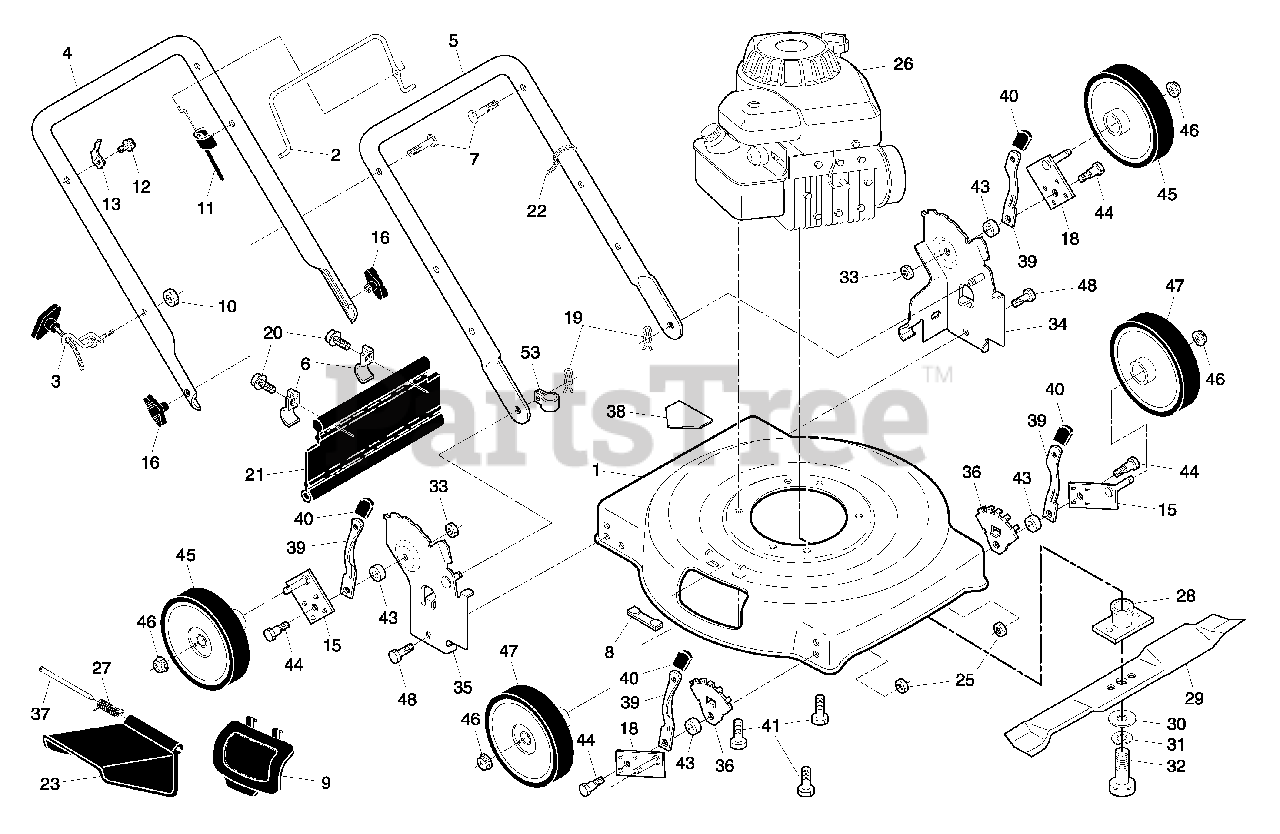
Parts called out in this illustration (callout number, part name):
1	Kit, Housing
2	Control Bar
3	Rope Guide
4	Upper Handle
5	Lower Handle
6	Shoulder Bolt 5/16-18 x 1/2
7	Handle Bolt 5/16-18
8	Clip, Closeout
9	Mulcher Plate
10	Locknut, Hex 1/4-20
11	Engine Zone Control Cable
12	Screw, Hex Head, Threaded, Rolled #10-24 x 1/2
13	Up-Stop Bracket
15	Axle Arm Assembly, Left Front & Right Rear
16	Handle Knob
18	Axle Arm Assembly, Right Front & Left Rear
19	Hairpin Cotter
20	Screw, Tapping, Hex Washer Head #10-24
21	Rear Deflector
22	Wire Tie
23	Discharge Guard
25	Nut, Hex, Flangelock 5/16-18
27	Torsion Spring
28	Blade Adapter
29	22" Blade
30	Hardened Washer
31	Helical Lockwasher 3/8
32	Screw, Hex Head, Grade 8, 3/8-24 x 1-3/8
33	Nut, Hex, Flangelock 5/16-18
34	Wheel Bracket Support (Left)
35	Wheel Bracket Support (Right)
36	Wheel Bracket Adjuster
37	Hinge Rod
38	Danger Decal
39	Selector Spring
40	Selector Knob
41	Screw, Hex Head, Threaded, Rolled 3/8-16 x 1
43	Spacer
44	Shoulder Bolt 5/16-18 x .33
46	Nut, Hex, Flangelock 3/8-16
47	Wheel & Tire Assembly
48	Screw, Hex Head, Serrated, Type TT 1/4-20
53	Clip, Cable
